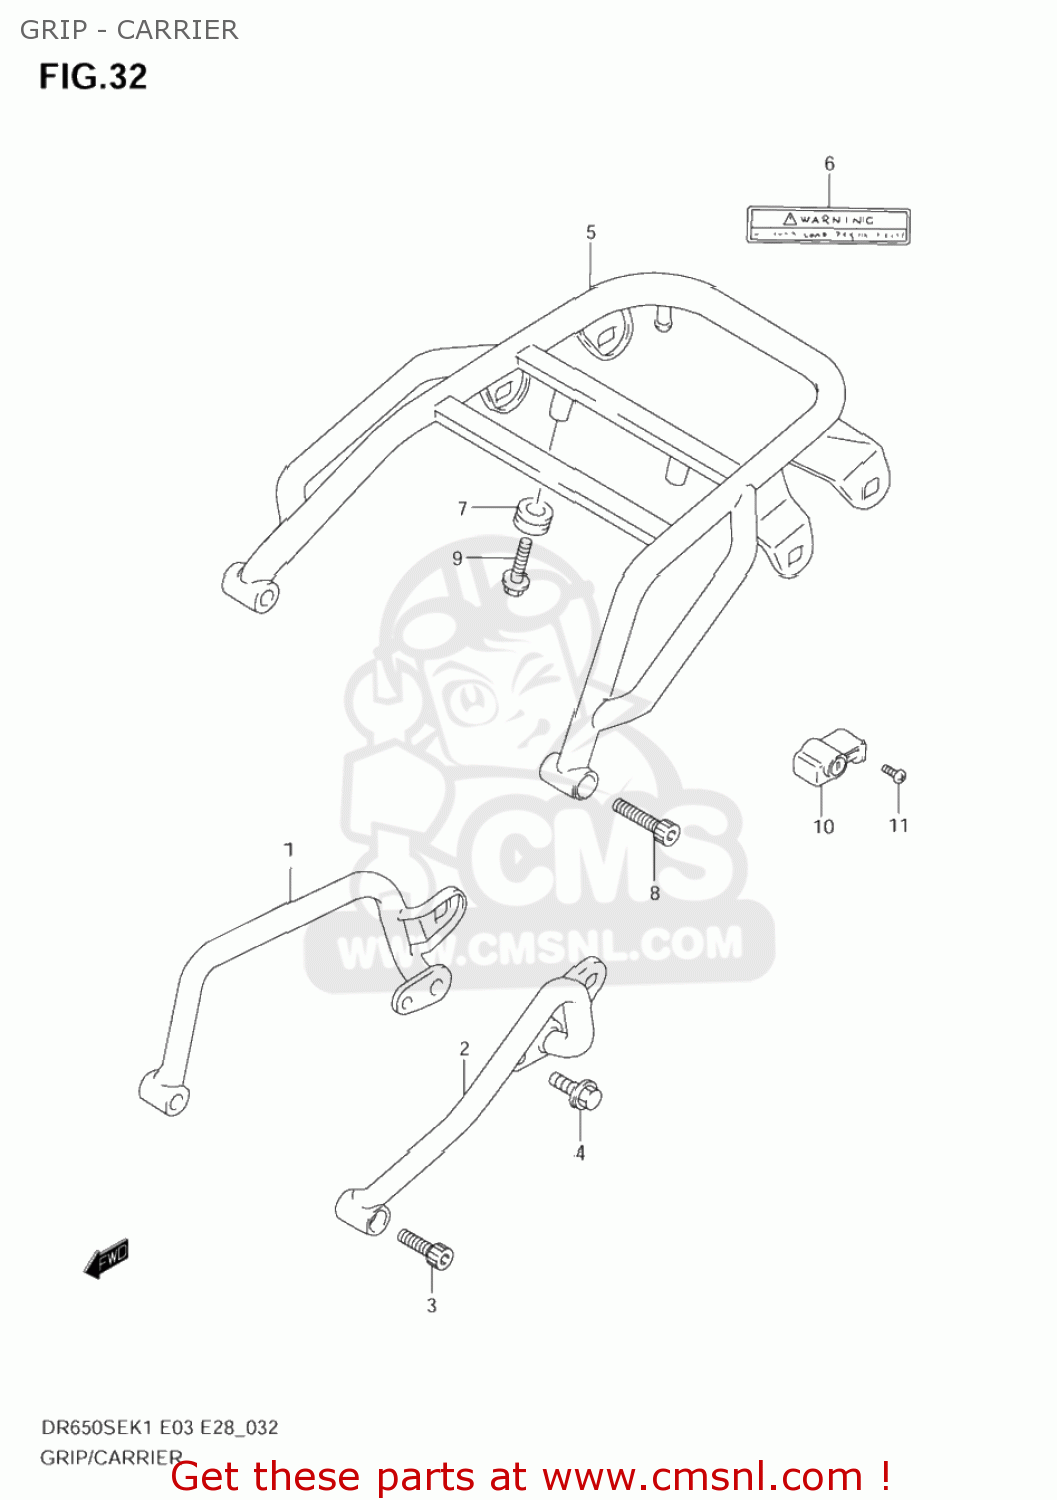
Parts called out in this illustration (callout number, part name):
1	GRIP,RR,R
2	GRIP,RR,L
3	BOLT
4	BOLT
5	REAR RACK SET,FOR E03
6	LABEL,WARNING RR CARRIER
7	GROMMET
8	BOLT
9	BOLT
10	LOCK SET,HELMET
11	SCREW(6X14)
